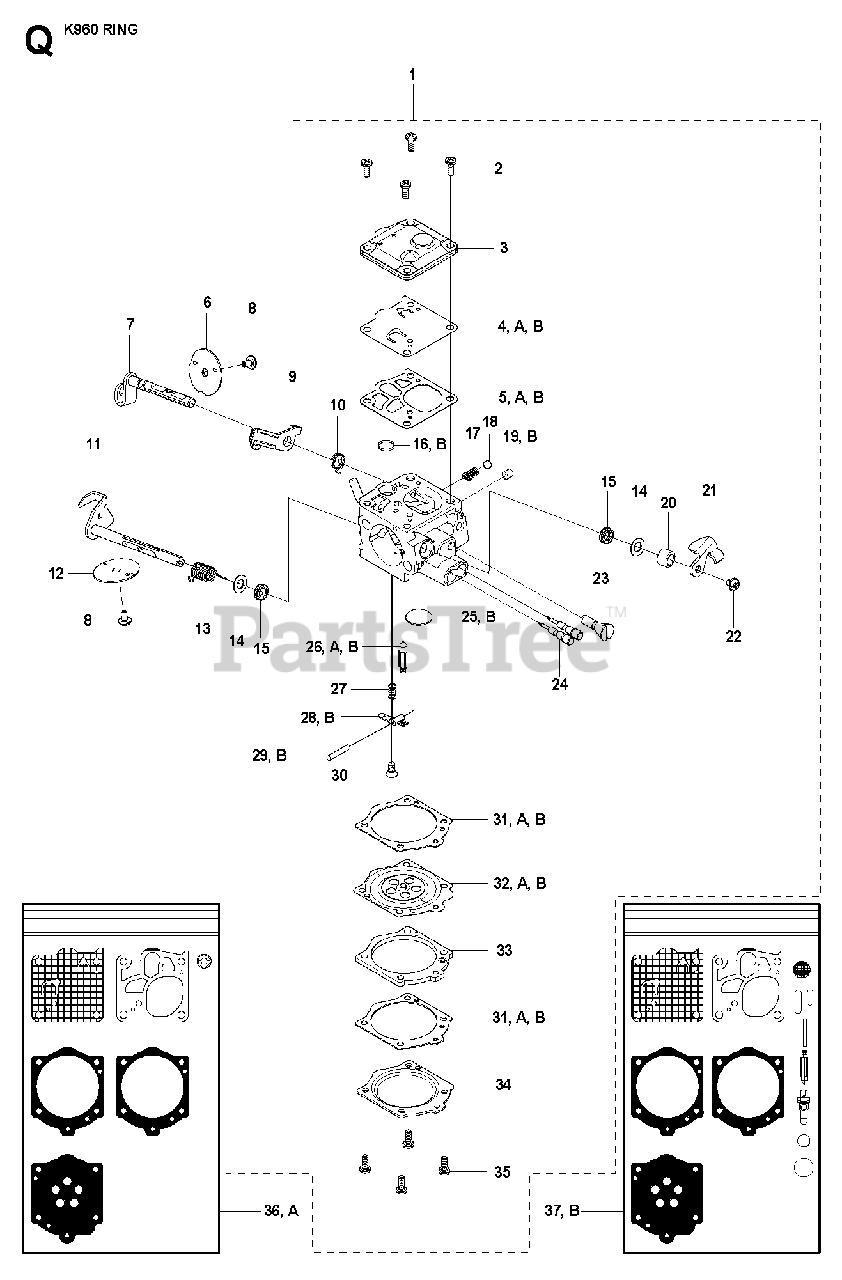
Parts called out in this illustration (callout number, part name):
1	CARBURETTORIncl. 2 - 32, Walbro RWJ-3
3	PUMP COVER
4	DIAPHRAGM PUMPA, B
26	VALVE -INLET NEEDLEA, B
29	PIN-METERING LEVERB
32	DIAPHRAGM ASSYA, B
36	GASKET KITKit A. D10-RWJ
37	REPAIR KITKit B. K10-RWJ
